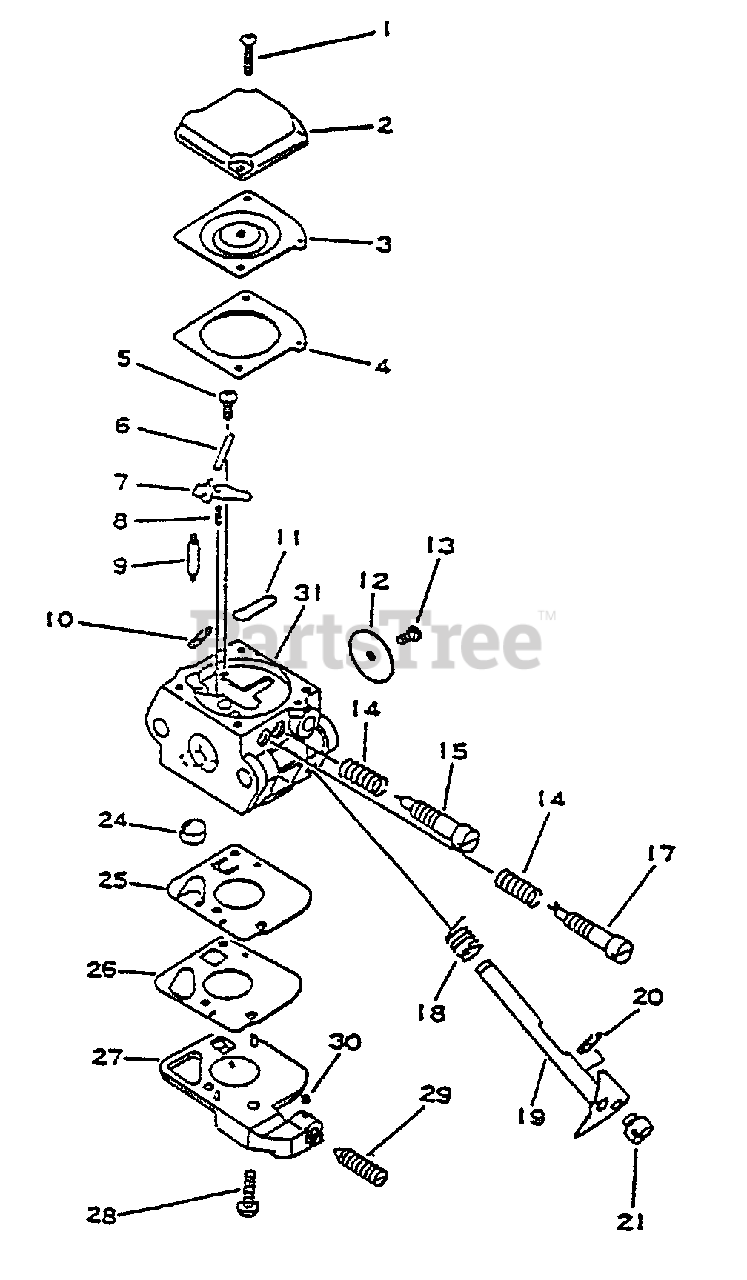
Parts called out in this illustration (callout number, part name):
2	COVER, METERING
3	DIAPHRAGM
4	GASKET, METERING
5	SCREW, METERING LEVER PIN
6	PIN, METERING LEVER
7	LEVER, METERING
8	SPRING
9	VALVE, NEEDLE
10	RING, RETAINING
11	PLUG, WELCH
12	VALVE, THROTTLE
13	SCREW
15	NEEDLE - HIGH SPEED
17	NEEDLE - LOW SPEED
18	SPRING, RETURN
19	SHAFT, THROTTLE
20	RING, RETAINING
24	STRAINER
25	DIAPHRAGM, PURGE
26	GASKET, PURGE
27	BASE, PURGE
28	SCREW, PUMP COVER
29	SCREW, IDLE ADJUST
30	PIECE, FRICTION
